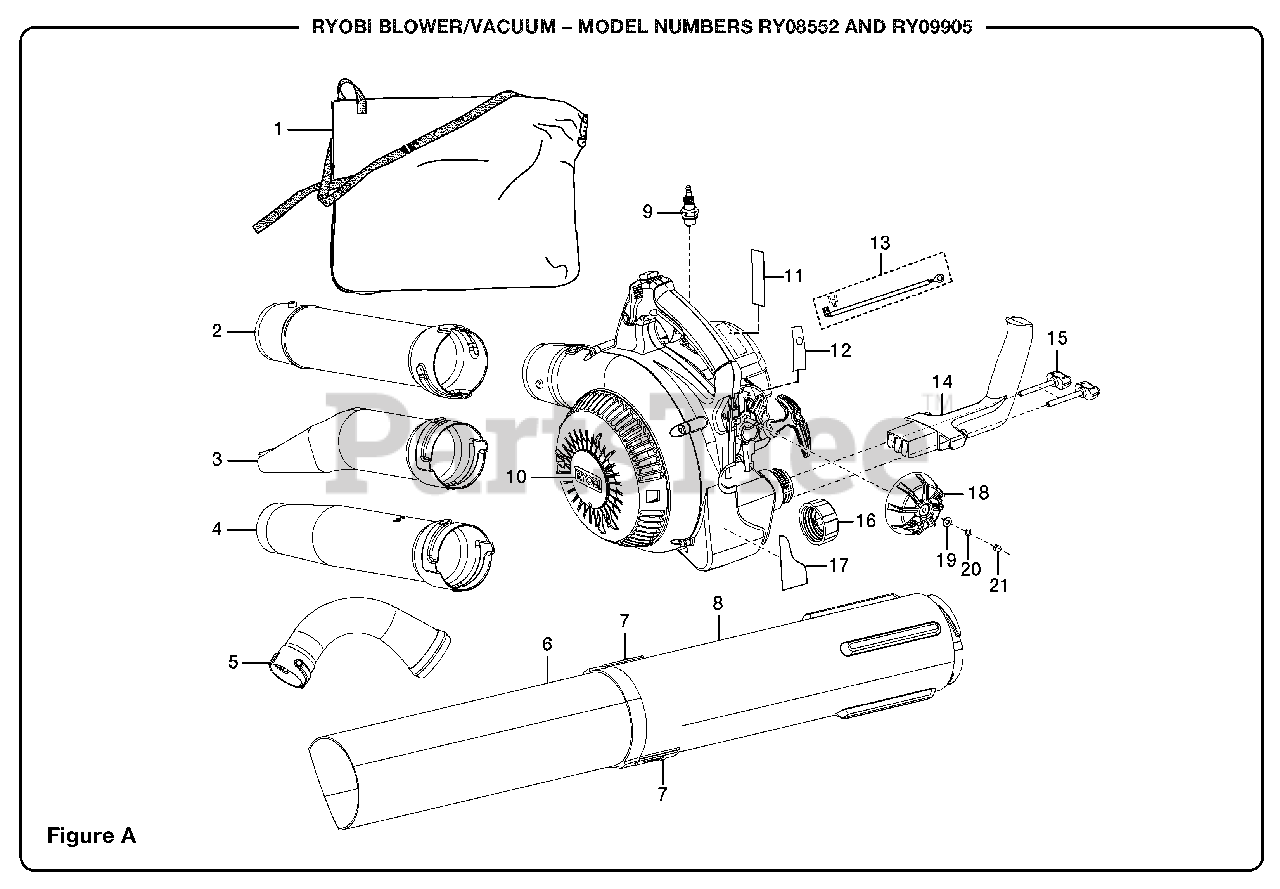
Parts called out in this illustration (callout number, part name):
1	Vacuum Bag w/Shoulder Strap
2	Upper Blower Tube
3	High Velocity Nozzle w/ Leaf Scraper
4	Sweeper Nozzle
5	Vacuum Bag Adaptor
6	Lower Vacuum Tube
7	Vacuum Tube Screw (10-14 x 1/2 in.)
8	Upper Vacuum Tube
9	Spark Plug
10	Vacuum Door Label
11	Starting Label
12	Choke Label
13	Ground Wire Kit
14	Vacuum Handle
15	Vacuum Handle Knob
16	Fuel Cap Assembly
17	Warning Label
18	Choke Dial Cover
19	Washer (M5)
20	Wavy Washer (M5)
21	Nylon Nut (M4)
